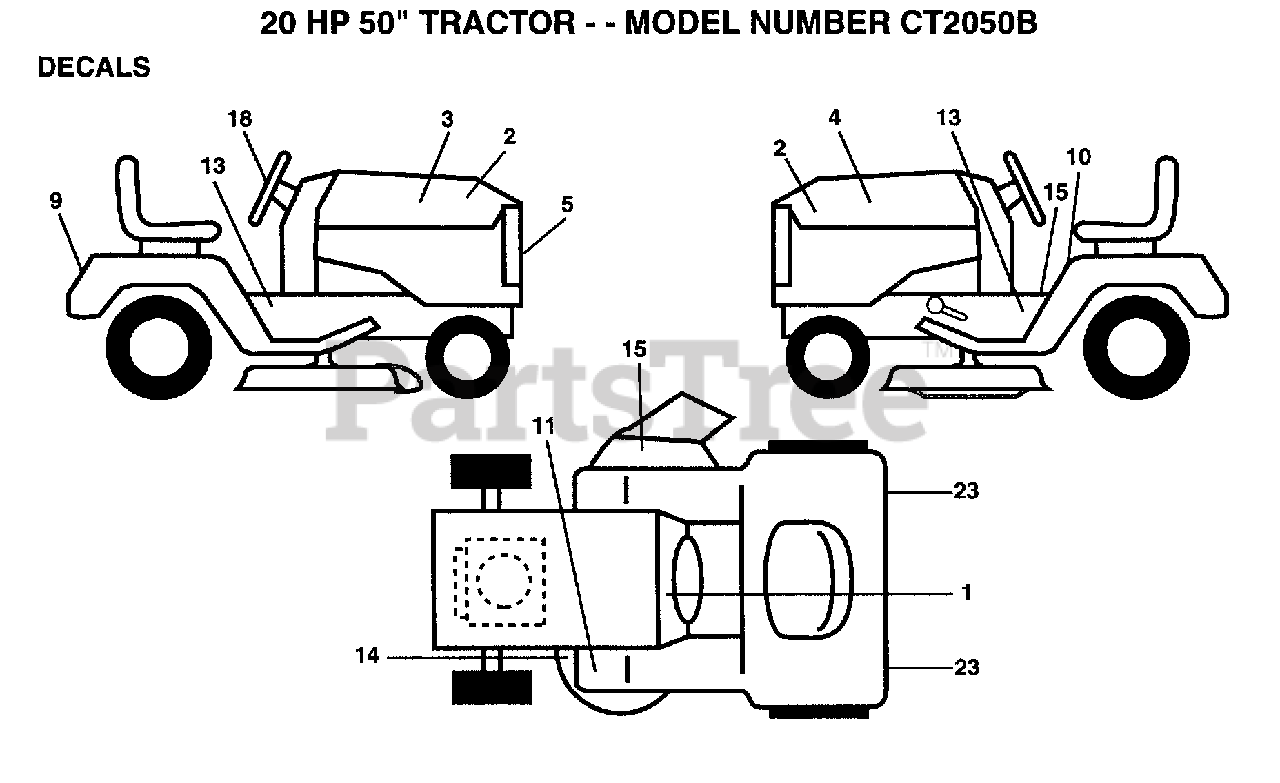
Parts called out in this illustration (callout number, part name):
1	DECAL.DASH.INST.
2	DECAL.HOOD.INS
3	DECAL.HOOD.RH.
4	DECAL.HOOD.LH.
5	DECAL.GRILLE
9	DECAL.FENDER
10	DECAL
13	DECAL.CHASSIS 6SP
14	"DECAL.V.BELT.44"""
15	"DECAL, WARNING"
18	DECAL INST STRWHL
23	REFLECTOR-TAIL YT
